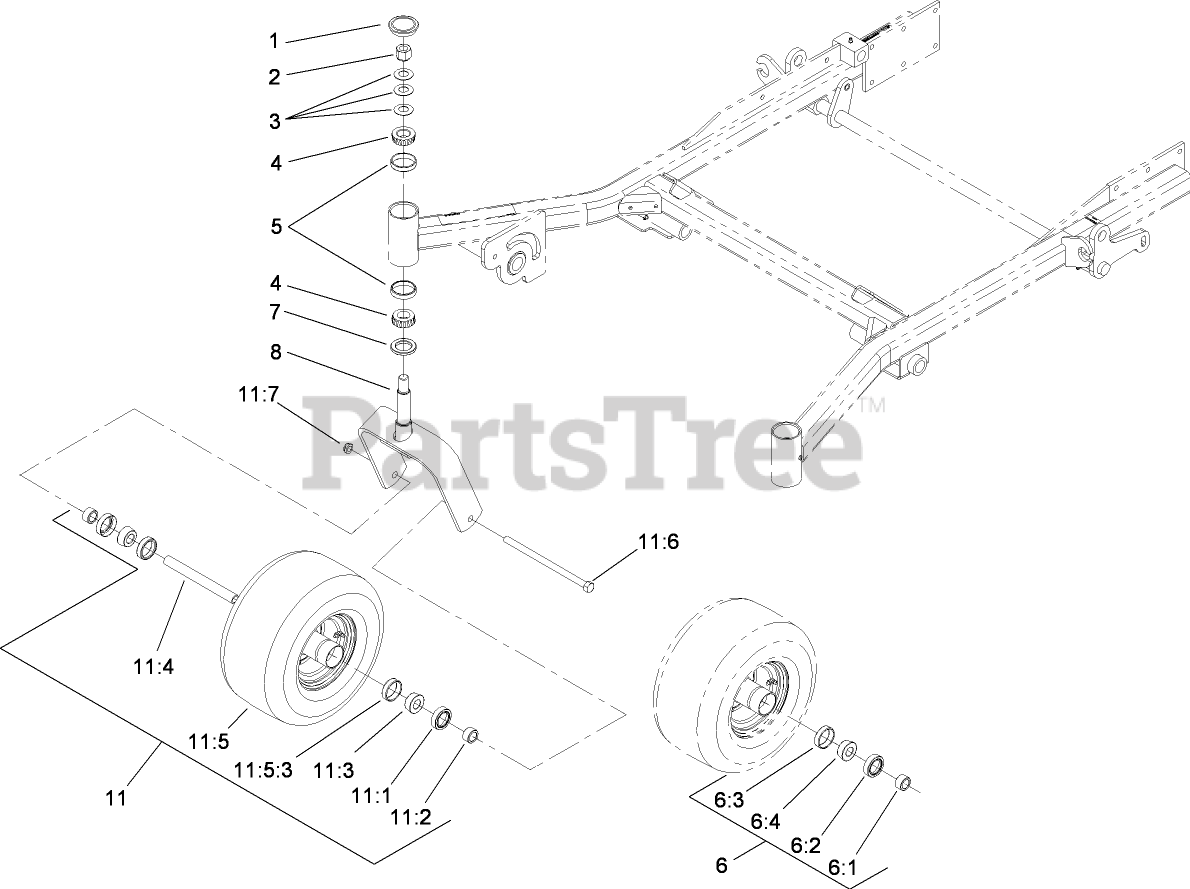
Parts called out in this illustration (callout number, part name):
1	CAP-GREASE
2	NUT-LOCK, NI
3	WASHER-BELLVILLE
4	BEARING-CONE, TAPERED
5	BEARING-CUP, TAPERED
6	CASTER WHEEL BEARING KIT
6:1	SPACER-BEARING
6:2	SEAL-BEARING
6:3	BEARING-CUP
6:4	BEARING-CONE, TAPER
7	SEAL-GREASE
8	CASTER-FORK
11	CASTOR WHEEL ASM
11:1	SEAL-BEARING
11:2	SPACER-BEARING
11:3	BEARING-CONE, TAPER
11:4	SPACER-CASTER, FRONT
11:5	WHEEL AND TIRE ASM (SEMI-PNEUMATIC)
11:5:3	BEARING-CUP
11:6	SCREW-HH
11:7	NUT-LOCK, NI
